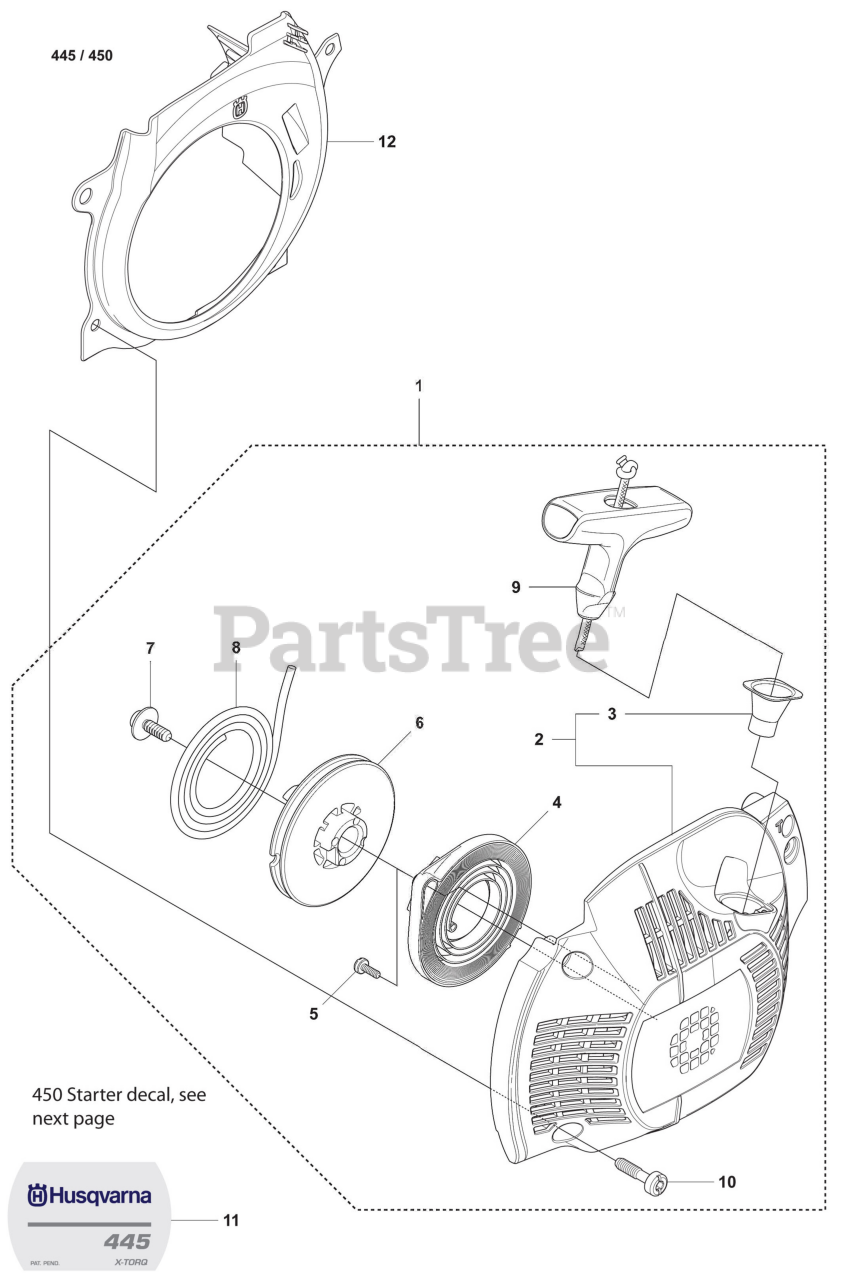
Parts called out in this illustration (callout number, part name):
1	Starter Assembly
2	Starter Housing
4	Return Spring
6	Starter Pulley
8	Starter Rope
10	Recoil Starter Screw
12	Air Cooling Conductor
